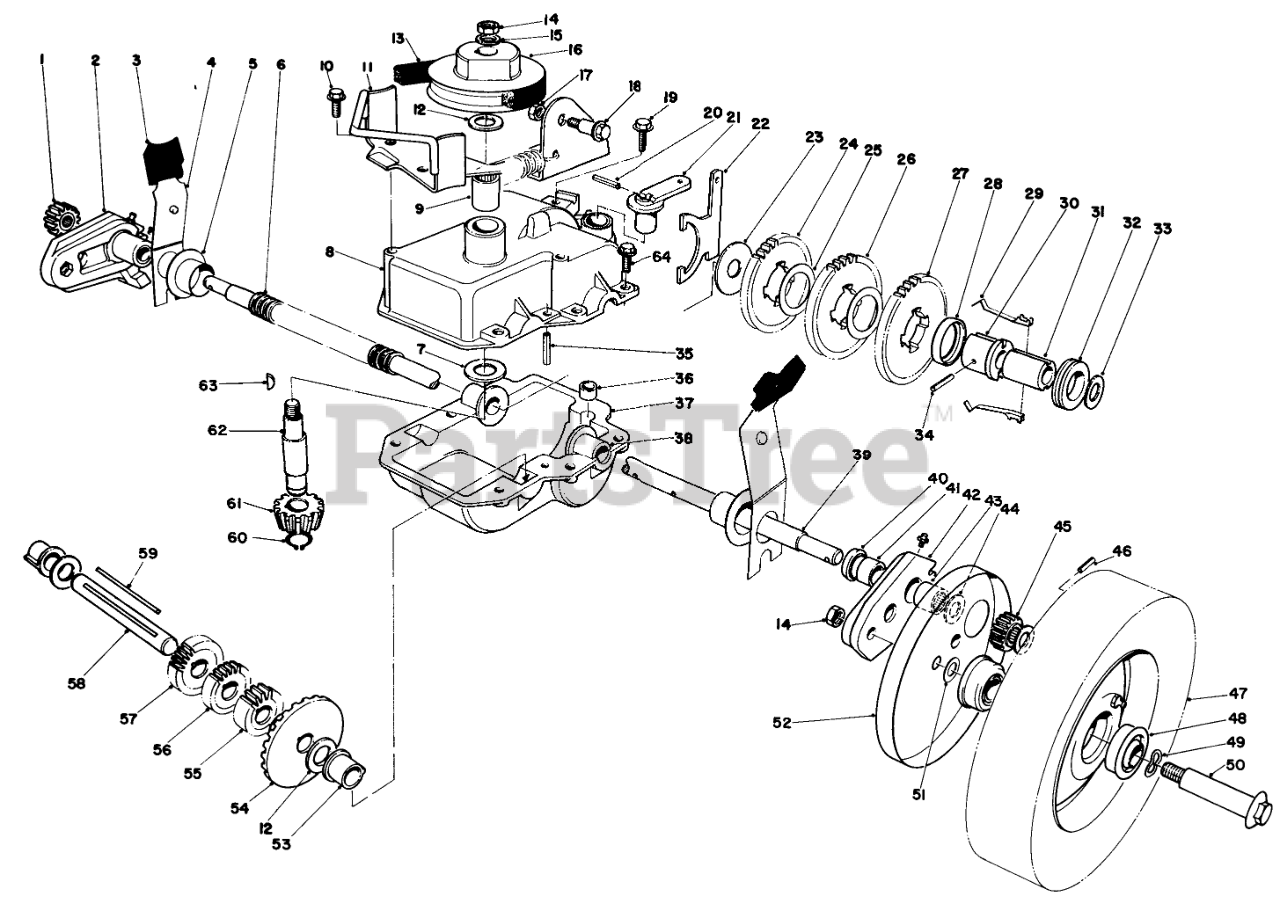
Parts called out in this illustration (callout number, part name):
1	RH CLUTCH & PINION
2	Pivot Arm R.H. (Incl. Ref. #40, 41 & 43)
3	KNOB-ARM
4	Spring Arm
5	CAP-END
6	CONDUIT-CONVOLUTED, SPLIT
7	Thrust Washer
8	Case-Upper
9	Bearing
10	Screw
11	Belt Guide Bracket
12	Washer
13	V-BELT
14	Nut
15	Washer
16	Pulley
18	SHOULDER BOLT
19	SCREW-HWHTF
20	PIN-COIL
21	LEVER-SHIFT
22	Shift Yoke
23	WASHER
24	Gear 35 Tooth
25	Washer
26	Gear 37 Tooth
27	GEAR-42T
28	KEY RETAINER
29	Key
30	Body-Sleeve
31	SLEEVE
32	COLLAR-SHIFT
33	Washer
34	PIN-SPRING
35	ROLL PIN 3/16 X 1 IN
36	BUSHING-YOKE
37	LOWER GEAR CASE CAST
38	Bushing
39	OUTPUT SHAFT
40	Seal
41	Bushing
42	Pivot Arm L.H. (Incl. Ref. #40-43)
43	Needle Baring
44	WASHER
45	LH CLUTCH & PINION
46	Pin
47	Wheel & Tire Assy. (Incl. Ref. #48)
48	BEARING-BALL
49	SPRING WASHER
50	Wheel Bolt
51	WASHER
52	Cover-Wheel
53	Botching Shaft
54	BEVEL GEAR
55	14 T GEAR
56	Gear 19 Tooth
57	Gear 21 Tooth
58	Sort Shaft
59	Key Square
60	RING-RETAINING
61	PINION-BEVEL
62	INPUT SHAFT
63	KEY-WOODRUFF
64	SCREW-HWH, THREAD ROLL
